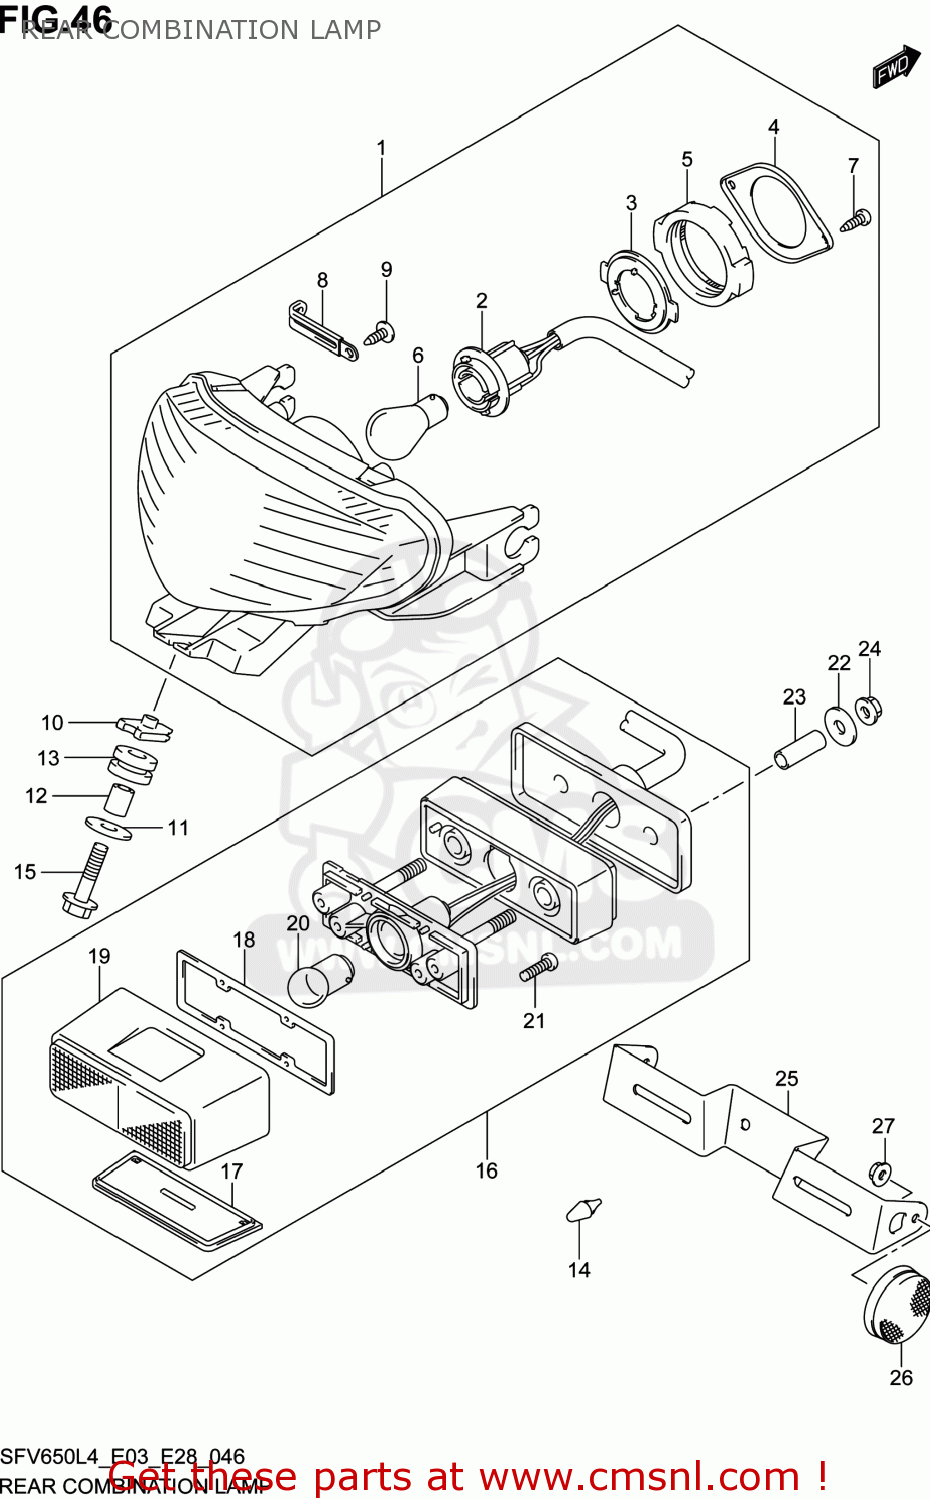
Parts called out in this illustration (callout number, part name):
1	LAMP ASSY,RR COMBINATION
2	SOCKET & CORD
3	PLATE NO.1
4	PLATE NO.2
5	CUSHION
6	BULB(12V21/5W)
7	SCREW
8	CLAMP(L:45)
9	SCREW
10	NUT
11	WASHER(5.5X20X1.2)
12	SPACER(5.5X9.5X10)
13	CUSHION
14	CUSHION
15	BOLT
16	LAMP ASSY,LICENSE
17	LENS,LICENSE LAMP
18	GASKET (NAS)
19	COVER,LICENSE LAMP
20	BULB(12V5W,BF150-40160A)
21	SCREW
22	WASHER(6.5X20X1.2)
23	SPACER(6.5X9X33.3)
24	NUT
25	BRACKET,LICENSE PLATE
26	REFLECTOR ASSY,RR SIDE
27	NUT
